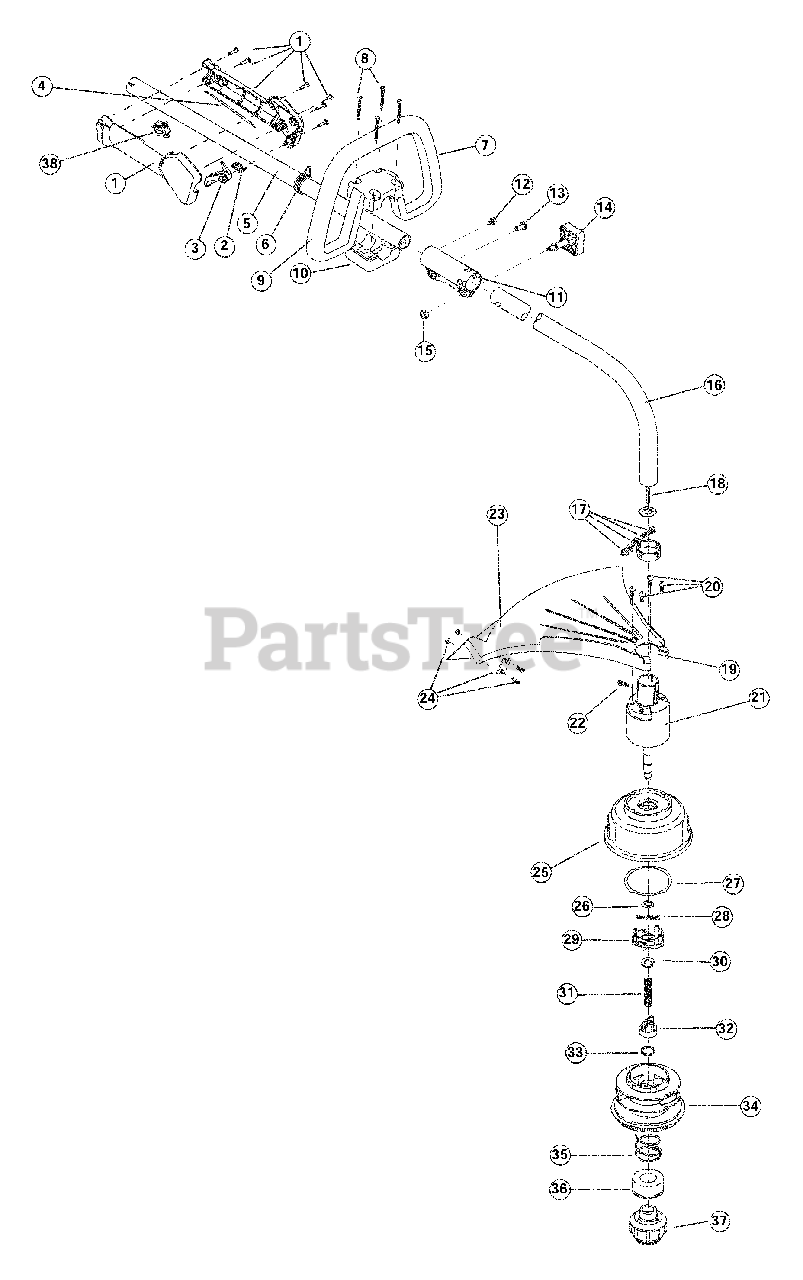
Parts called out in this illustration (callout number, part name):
1	Throttle Housing and Trigger Assembly
2	Throttle Trigger Spring
3	Throttle Trigger
4	Throttle Cable Assembly
5	Upper Drive Shaft Housing Assembly
6	Harness Clip
7	Deluxe D-Handle Assembly
9	Deluxe D-Handle
10	Bottom Clamp
11	Split-Boom Coupler
14	Adjustment Knob
15	Knob Retaining Nut
16	Lower Drive Shaft Housing Assembly
17	Lower Clamp Assembly
18	Lower Flexible Drive Shaft
19	Palnut
20	Shield Mounting Screw
21	Bushing Housing Assembly
22	Anti-Rotation Screw
23	Shield and Blade Assembly
24	Blade Assembly
25	Outer Spool and Eyelet Assembly
27	Thrust Washer
28	Small Spring
34	Inner Reel
35	Large Spring
37	Bump Head Knob Assembly w/Spring & Foam Seal
38	Switch Assembly
